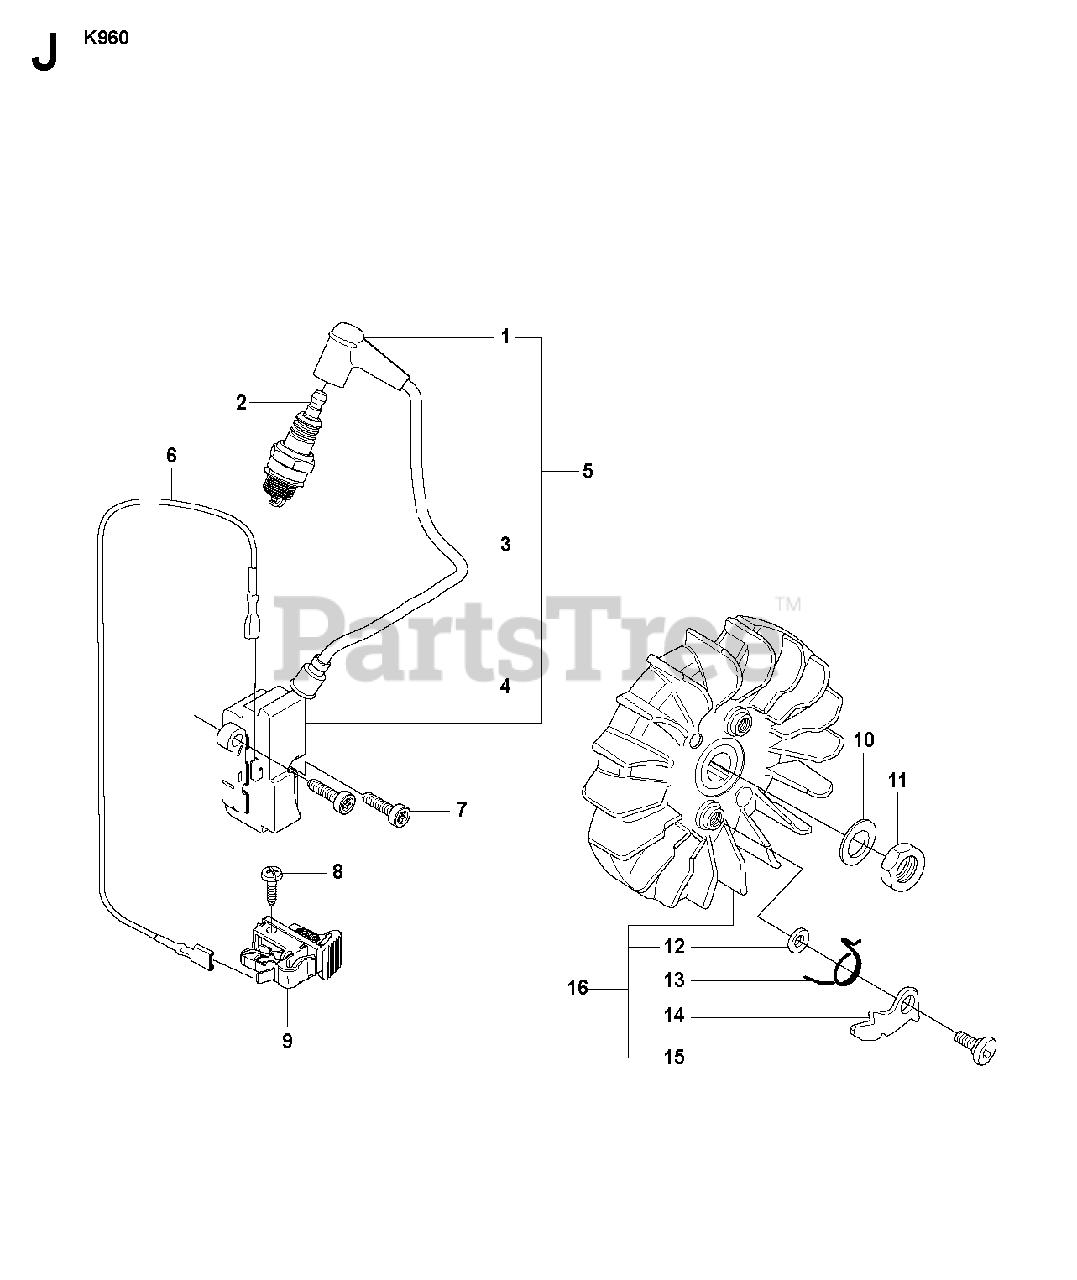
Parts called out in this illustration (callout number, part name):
1	SPARK PLUG CAP
3	IGNITION CABLE
5	IGNITION MODULEIncl. 1, 3, 4
7	SCREW ITXSCM
8	SCREW CCRPANT
9	STOP SWITCH
16	FLYWHEELIncl. 12 - 15
